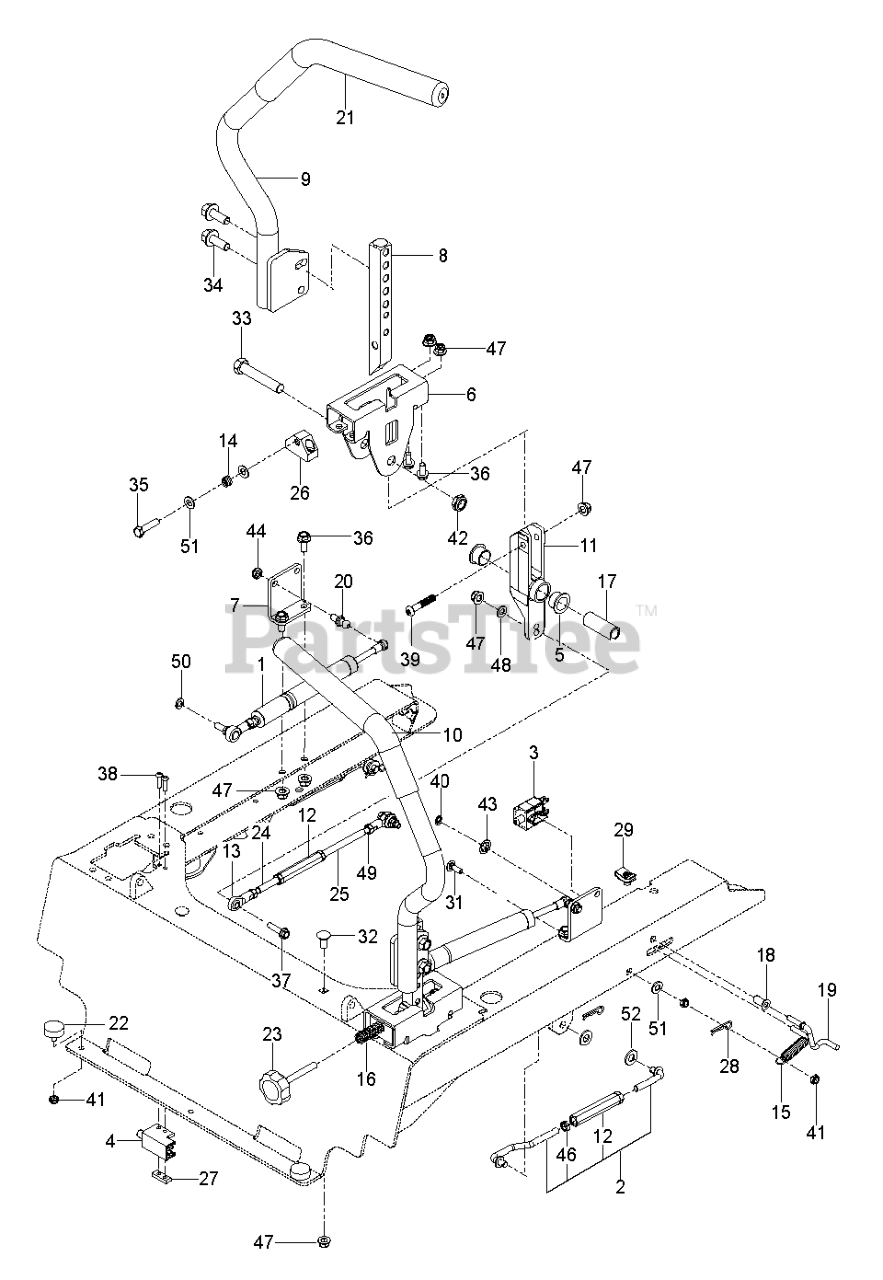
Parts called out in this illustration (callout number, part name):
1	ASSEMBLY, DAMPENER
2	SWITCH, BRAKE 3P
3	SWITCH, BRAKE 3P
4	SWITCH, INTERLOCK
5	BEARING, FLANGE
6	BRACKET.CONTROL.NARROWSLOT.BLK
7	BRACKET.DAMPNER
8	LEVER, MOTION
9	LEVER.WITH GRIP.RT
10	LEVER.WITH GRIP.LT
11	LEVER.CONTROL.SHORT
12	TURNBUCKLE, 3/8
13	BALL JOINT, RIGHT HANDED
15	SPRING, EXTENSION
16	SPRING COMPRESSION 2.0
17	SPACER, PIVOT CONTROL
18	BUSHING, 1/4 FLANGE
19	LINK, SWITCH
20	STUD.BALL.10MM
21	GRIP - DRIVE LEVER 12"
22	NUT
24	LINKAGE, CONTROL, FT
25	LINKAGE, CONTROL, RR
26	BLOCK TRACKING CONTROL ZTR
27	PLATE NUT ZTR
28	HAIRPIN #2
29	U-CLIP 5/16-18 NUT RETAINER
30	BOLT
31	BOLT 5/16C X 3/4" CARRIAGE
32	HHFS 5/16-18 X 1.25 TPBLT GD 5
33	HCS 1/2-13 X 2-3/4 GD 5 ZD
34	HHFS 3/8-16 X 1 GRD 5 ZD
35	BOLT.5/16-18X1-1/4 FULL.THREAD
36	HHFS 5/16-18 X 3/4
37	SCREW 5/16-18 X 1 3/4 BTN-HD
38	SCR #10-24 X .75 SKT HD BLK
39	SCREW 5/16-18 X 1 3/4 BTN-HD
41	JAM NUT 1/4C (2 2 PW01)
42	NUT 1/2-13 HEX JM NYL
43	NUT 3/8 PALNUT RTNG BLK PHOS
44	NUT.71038.31-18.HEX.NYLOCK
46	NUT 3/8-24 JAM
47	5/16-18 NYLOC FLANGE NUT
48	WASHER
49	WASHER 5/16 FLAT
50	WASH.5/16.SLW.ZD
51	WASHER
